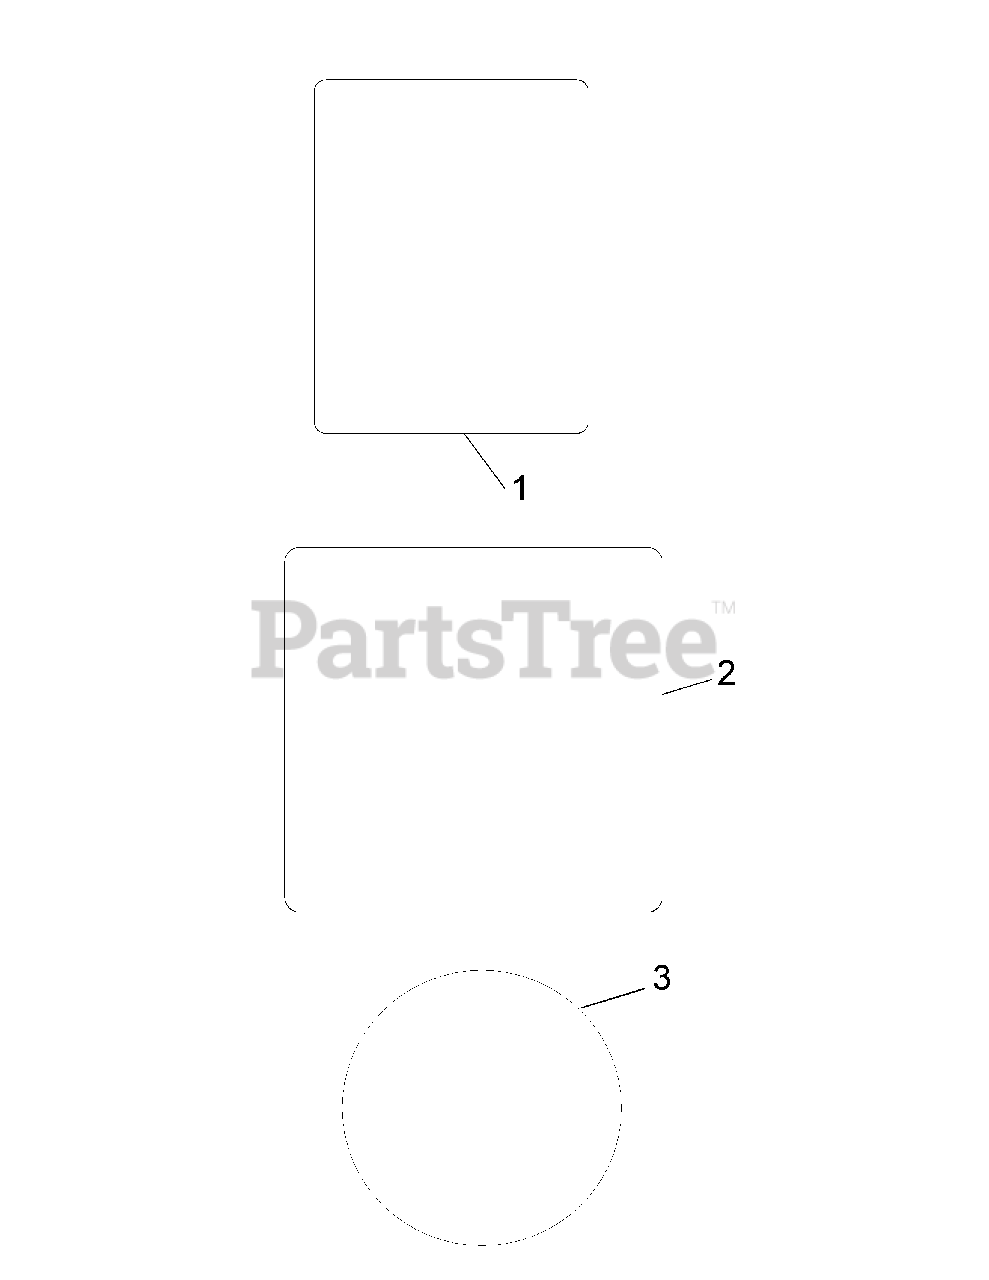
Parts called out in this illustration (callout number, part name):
1	Clear Laminate Decal
2	HDAC 747cc/CV-CH732 Decal
3	Grass Screen Decal
